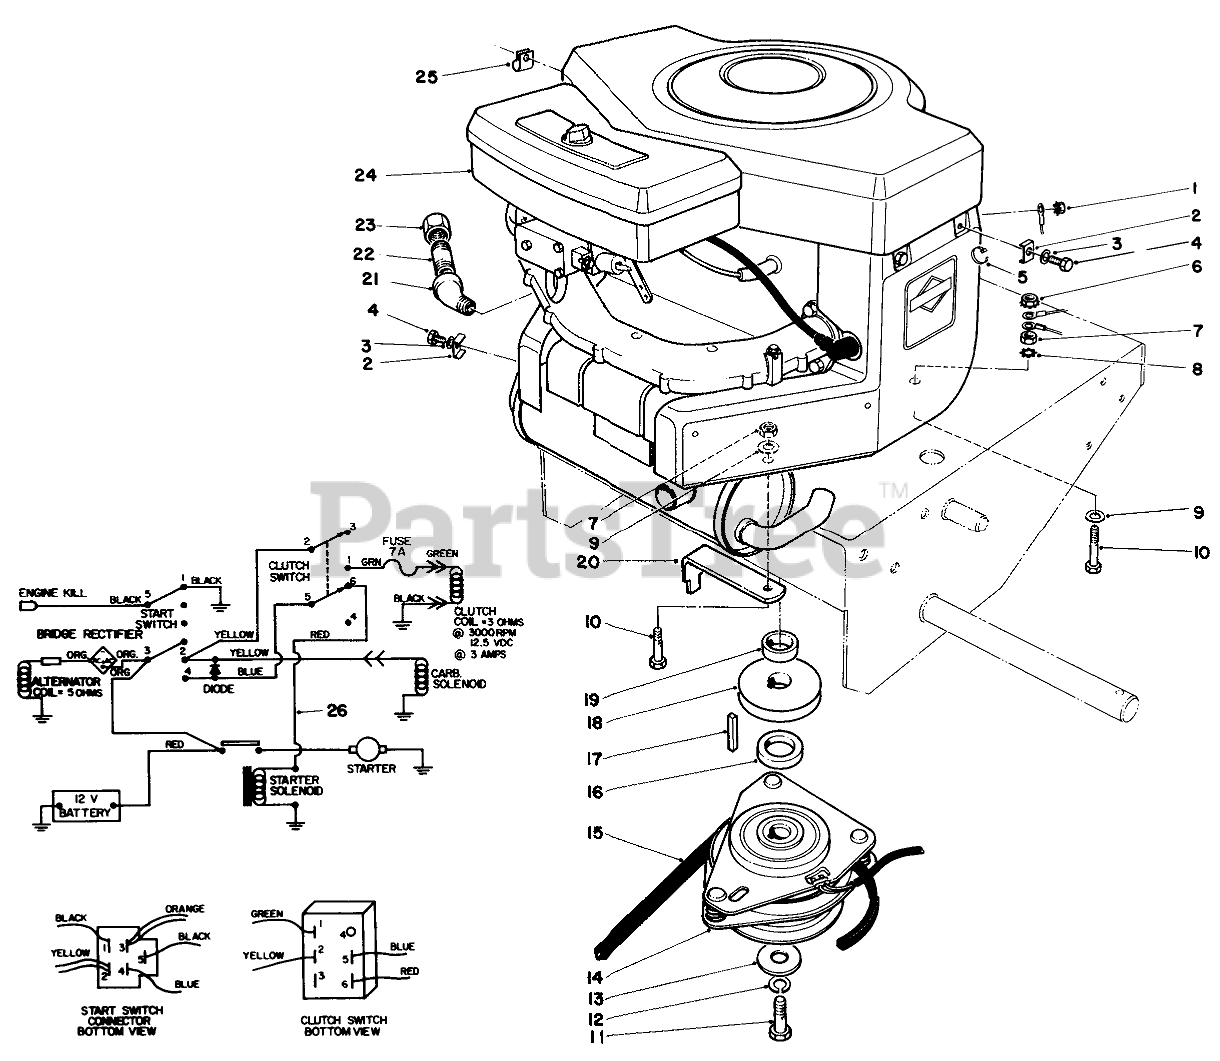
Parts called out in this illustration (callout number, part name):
1	NUT-KEPS
2	CLAMP-CABLE
3	WASHER-LOCK
4	SCREW-HH
5	TIE-CABLE
6	NUT-KEPS
7	NUT-LOCK, CONE
8	WASHER-LOCK
9	WASHER-PLAIN
10	SCREW-HH
11	SCREW-HH
12	WASHER-LOCK
13	WASHER-CLUTCH
14	CLUTCH/BRAKE
15	V-BELT, DRIVE
15	V-BELT
16	SPACER-LOWER
17	KEY-SQUARE
18	Pulley-Drive
19	Spacer-Upper
20	Retainer-Clutch
21	ELBOW
22	NIPPLE
23	CAP-PIPE
24	Engine
25	CLAMP-R
26	16 HP WIRE HARNESS
